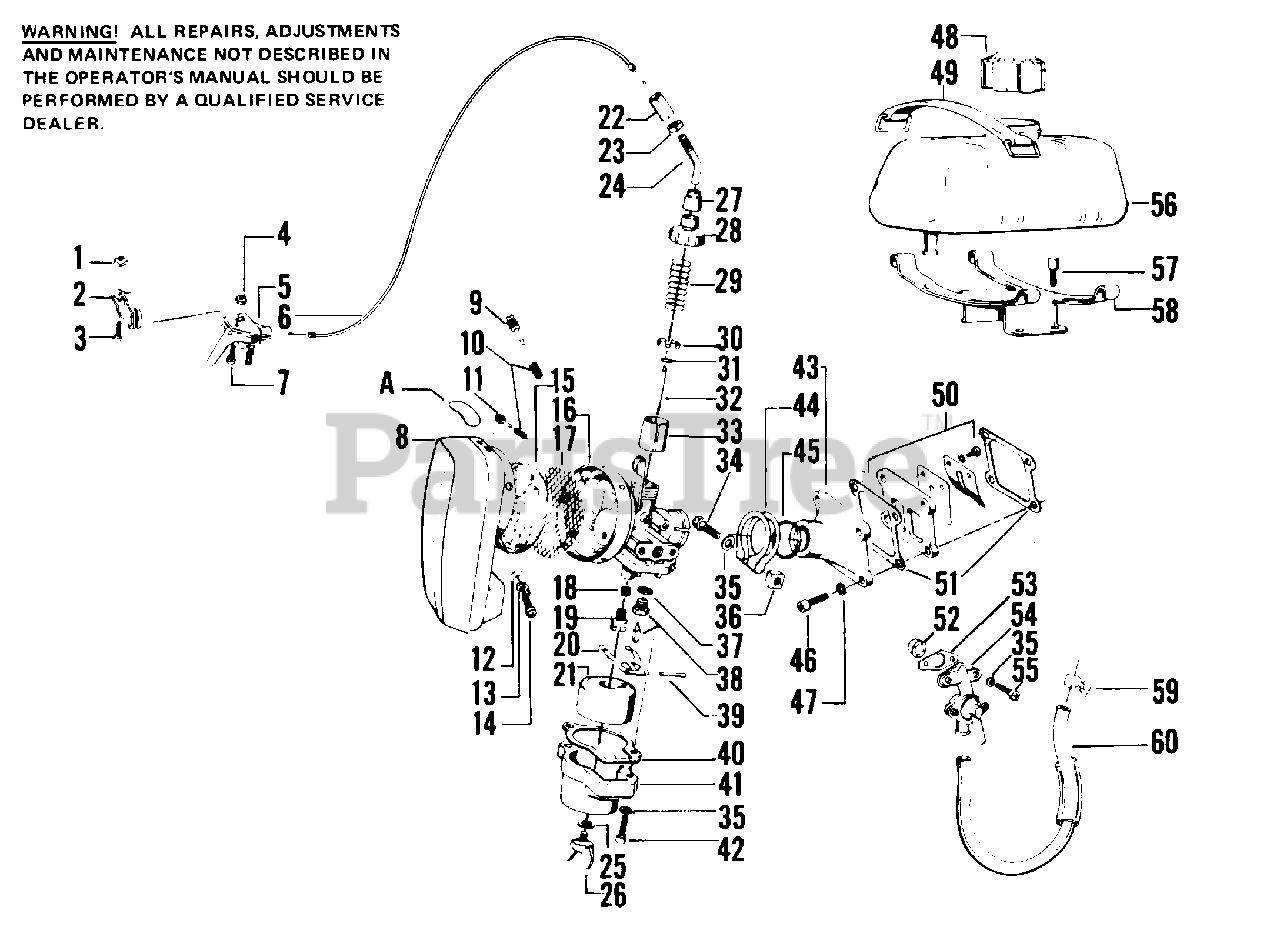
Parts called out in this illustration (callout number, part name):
1	Nut - Throttle Control Clamp
2	Clamp - Throttle Control
3	Bolt - Throttle Control Clamp
4	Wing Nut - Throttle Control
5	Throttle Control
6	Throttle Cable
7	Screw Throttle Control
8	Silencer Assembly
9	Screw - Air Bleed
11	Screw - Throttle Stop
12	Flat Washer
13	Spring Washer
16	Carburetor Assembly (Incl. 9, 10, 11, 22-33, 37,-42)
18	Jet - Pilot
19	Main Jet
20	Float Hinge
22	Throttle Cable Bushing
23	Cable Adjusting Nut
24	Cable Adjuster
25	Fiber Washer
26	Drain Screw
27	Rubber Grommet
29	Throttle Spring
30	Spring Seat
32	Needle Jet
33	Piston Valve
36	Square Nut
38	Needle Valve Assembly
39	Float Hinge Pin
41	Float Chamber
43	Carburetor Bracket
45	"O" Ring
47	Lock Washer
48	Fuel Tank Cap Assembly
49	Tank Band
50	Reed Valve Assembly
54	Valve - Fuelflow
56	Fuel Tank
58	Fuel Tank Bracket Assembly
59	CLAMP 10805-01 Z
60	Fuel Pipe Assembly
A	Choke Decal
